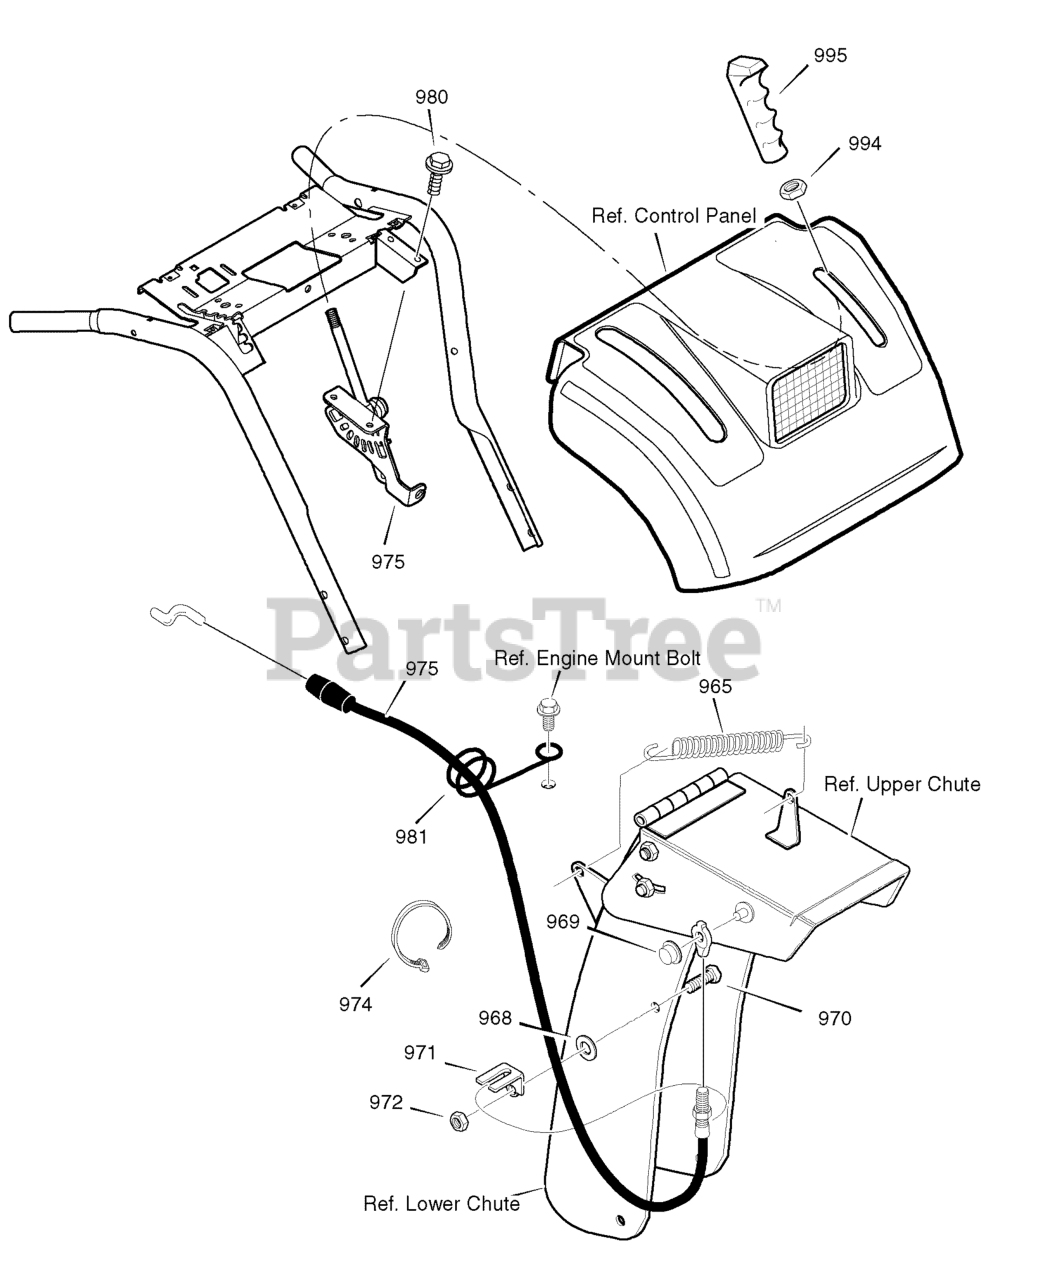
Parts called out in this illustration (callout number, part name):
965	TENSION SPRING
968	FLATWASHER
969	PUSH NUT
970	SCREW, 5/16-18 X 0.75
971	BRACKET, CABLE CHUTE
972	NUT, 5/16-18
974	TIE, CABLE
975	LEVER & CABLE, CHUTE DEFLECTOR
980	SCREW
981	WIRE FORM, CHUTE CABLE
994	NUT, 3/8-16
995	KNOB, SHIFT
